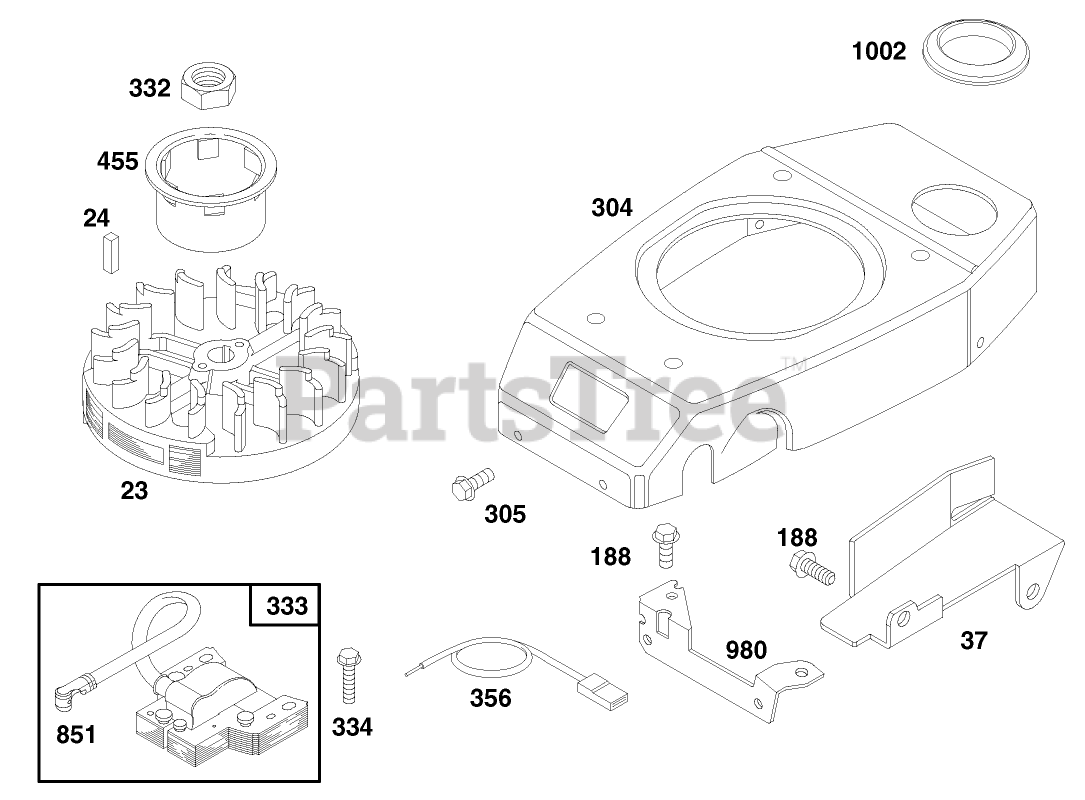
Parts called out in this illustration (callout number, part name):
24	KEY - FLYWHEEL
37	GUARD - FLYWHEEL
304	HOUSING - BLOWER
305	SCREW - HEX HEAD
332	NUT - HEXAGON
356	WIRE - GROUND
980	BRACKET-BLOWER HSG
